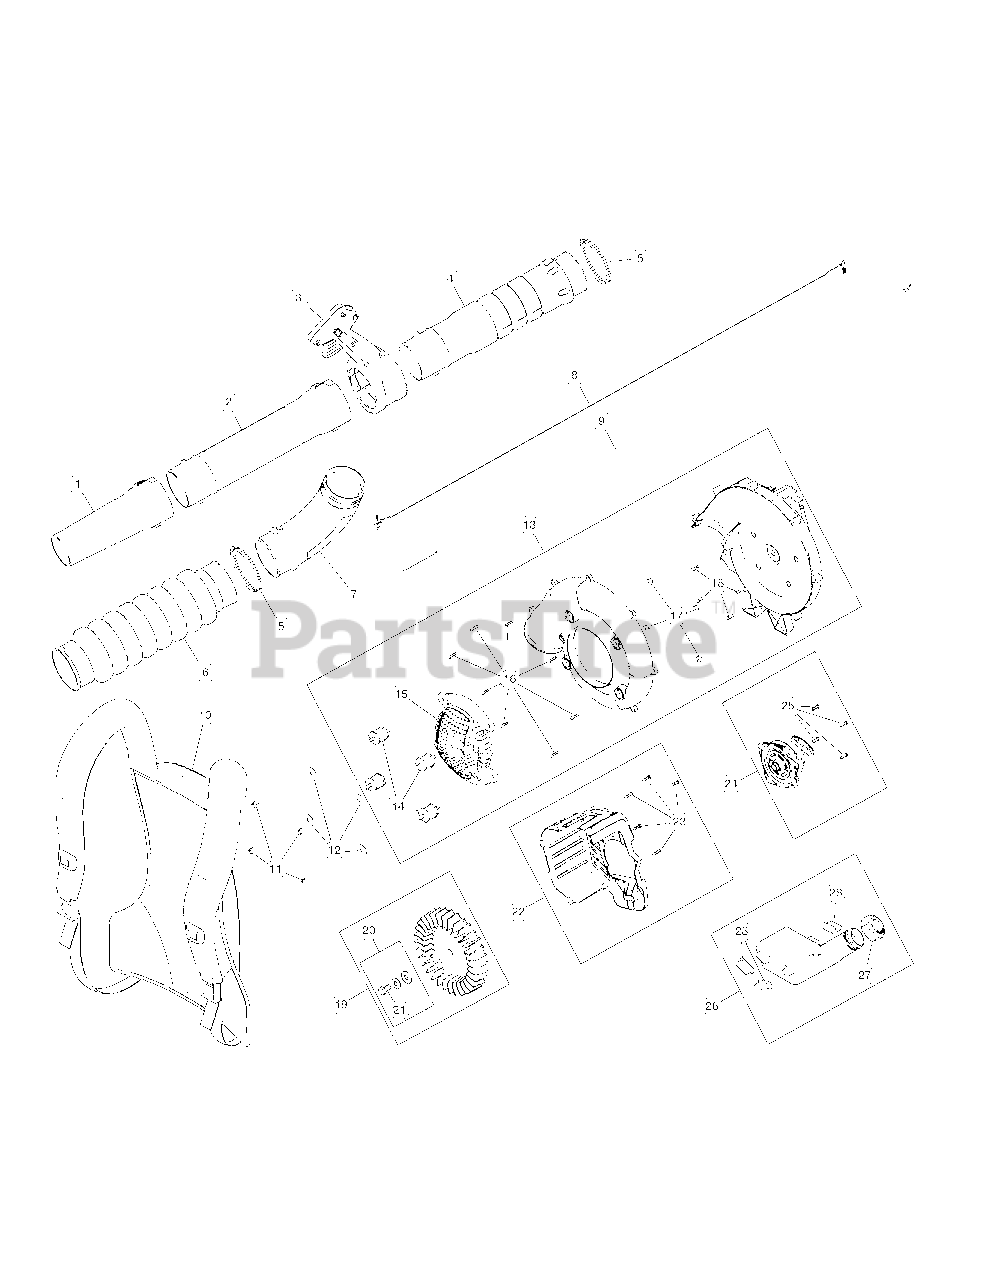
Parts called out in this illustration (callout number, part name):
1	Nozzle
2	Lower Blower Tube
3	Throttle Grip Assembly
4	Upper Blower Tube
6	Flex Tube
8	Lead Wire
9	Throttle Cable
10	Harness
11	Nut
12	Washer
13	Impeller Housing Assembly (Incl. 14 - 18)
14	Insulator Mount
15	Intake Cover
17	Nut
18	Screw
19	Impeller (Incl. 20 & 21)
20	Impeller Hardware (Incl. 21)
22	Housing Assembly (Incl. 23)
24	Starter Assembly (Incl. 25)
25	Screw
26	Fuel Tank Assembly (Incl. 27 & 28)
27	Fuel Cap
28	Fuel Tank Pads
